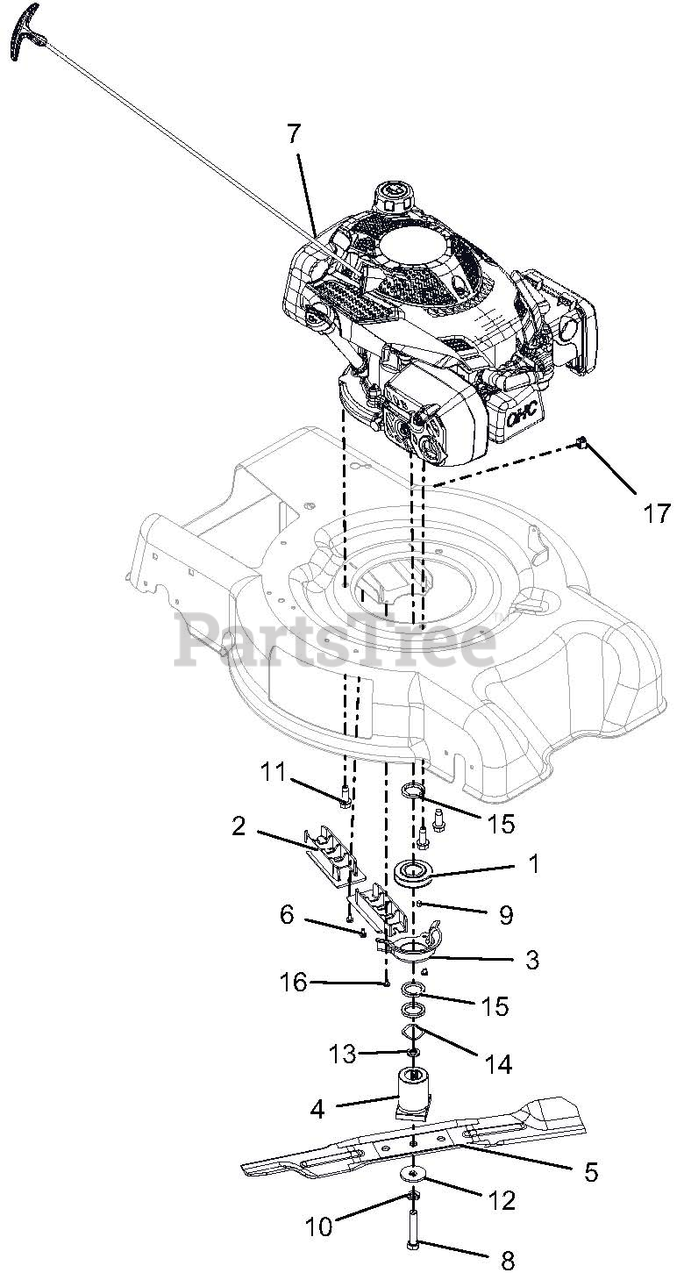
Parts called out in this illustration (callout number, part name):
1	PULLEY,MACHINED POWDER METAL
2	GUIDE, BELT INNER
3	GUIDE, BELT CRANK
4	ADAPTER, BLADE
5	BLADE, MOWER 21" HIGH LIFT
6	SCR-TAP 10-24X.375 PRE-COAT 80
7	ENGINE, SUBARU 175CC VERT. ES
8	@BLT-HEX .4375-20X2.25 GR8 YWZ
9	KEY-SQ .188X.188X.250
10	@WSHR-LK .44X.109 REG YWZC
11	@SCR-TAP .38-16X1.00 HWH TR YZ
12	WSHR-FL-STL .4375X1.50X.125 YZ
13	WSHR-FL-STL .459X.750X.105 YZC
14	WASHER - WAVE 1.09X1.37X.016
15	SPCR, 1.00 X 1.375 X .179
16	SCR-TAP 10-24X.25 CRSLPH TR YZ
17	PLUG, DOME-BLACK, .625 DIA
